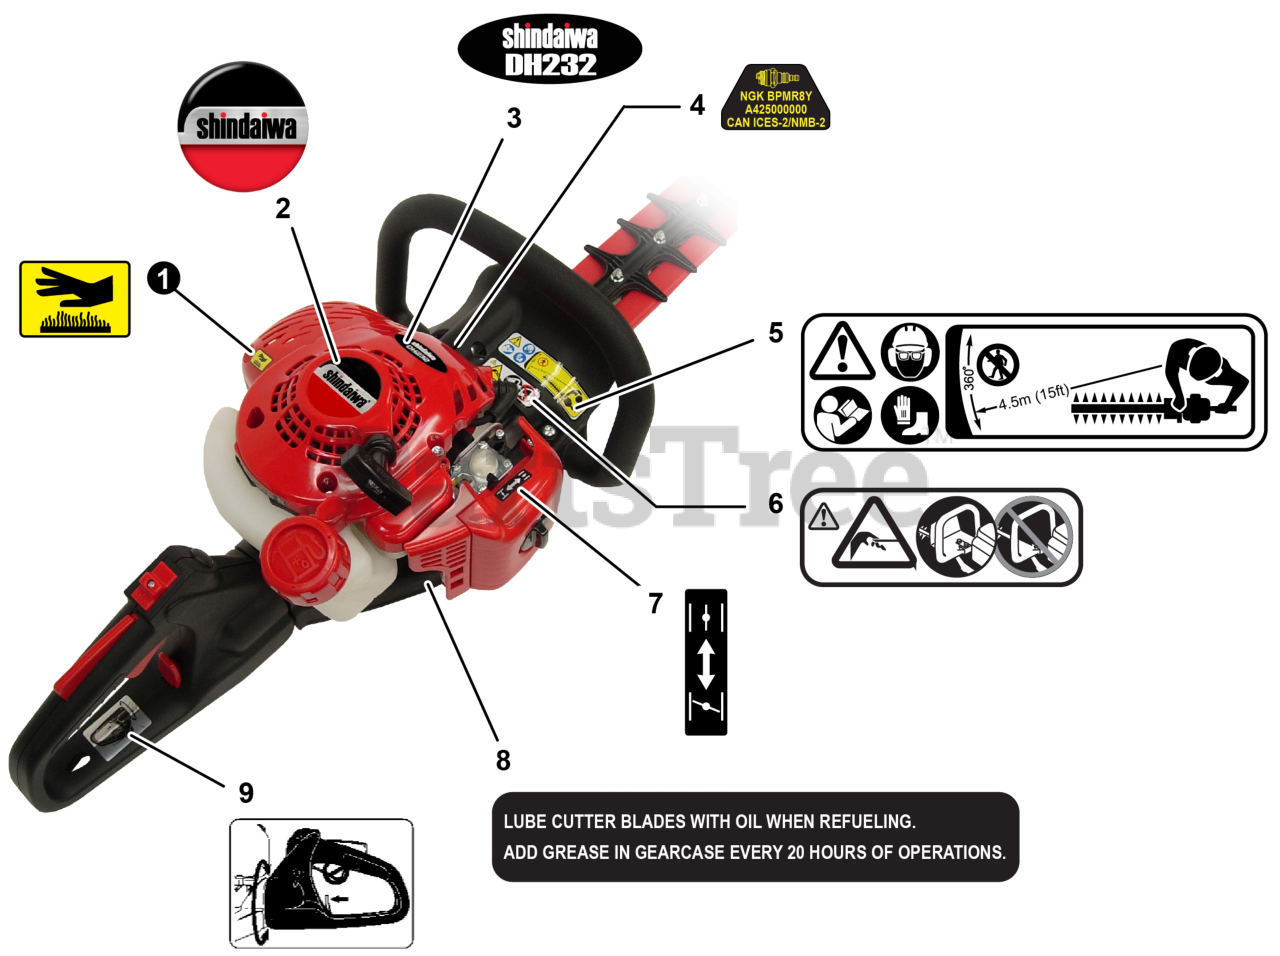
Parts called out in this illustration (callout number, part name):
1	LABEL - CAUTION - HOT
2	LABEL - SHINDAIWA
3	LABEL DH232
4	LABEL - SPARK PLUG - BPMR8Y
5	LABEL - CAUTION - ISO
6	LABEL - CAUTION
7	LABEL - CHOKE
8	LABEL - LUBE BLADES
9	LABEL - CAUTION
